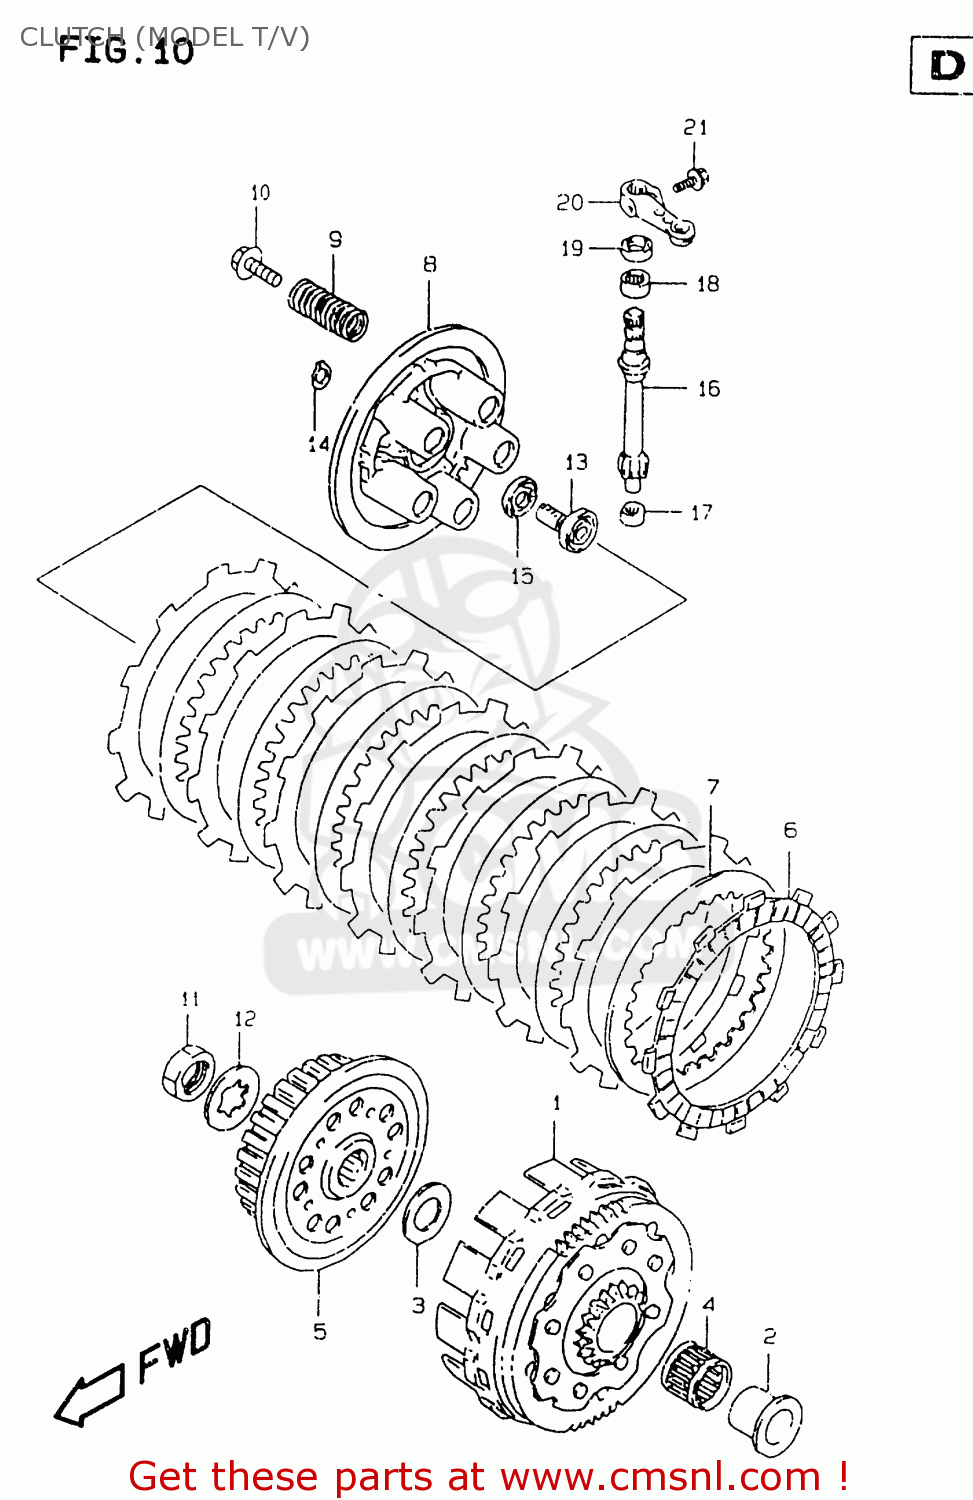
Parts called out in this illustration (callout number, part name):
1	GEAR ASSEMBLY,PRIMARY (NT:6
2	SPACER,PRIMARY DRIVEN GEAR
3	WASHER
4	BEARING(25X30X22)
5	HUB,CLUTCH SLEEVE
6	PLATE,CLUTCH DRIVE(T:2.8) (NAS)
7	PLATE,CLUTCH DRIVEN(T:1.4) (NAS)
8	DISC,CLUTCH PRESSURE
9	SPRING
10	BOLT(5X25)
11	NUT
12	WASHER,LOCK
13	RACK,CLUTCH RELEASE
14	CIRCLIP,10MM
15	BEARING(10X22X2.8)
16	PINION,CLUTCH RELEASE(NT:12)
17	BEARING(9X13X10)
18	BEARING(12X16X10)
19	SEAL,OIL(10X17X5)
20	ARM,CLUTCH RELEASE
21	BOLT
